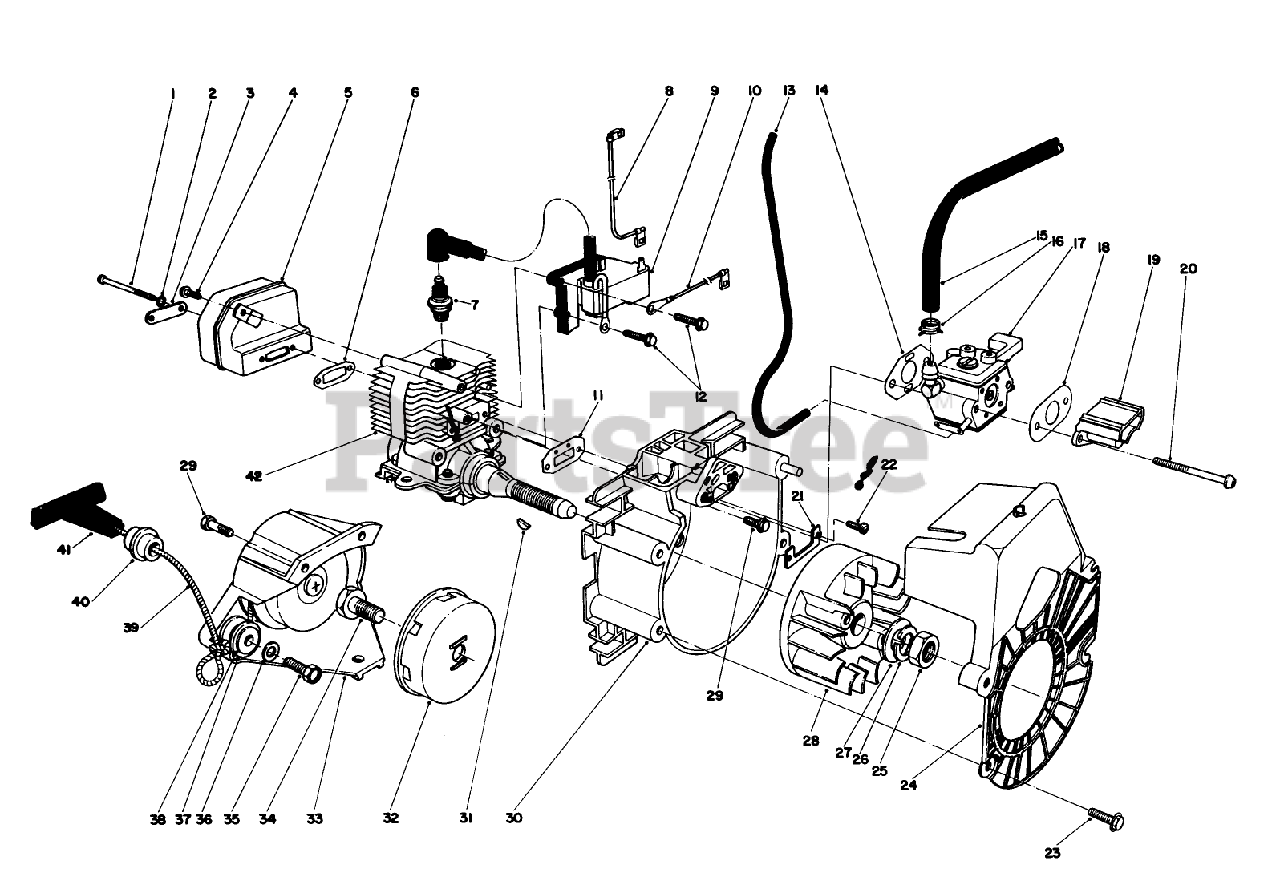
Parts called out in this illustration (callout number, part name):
1	MUFFLER SCREW
2	LOCKWASHER
3	Stress Plate, Muffler
4	Screw, Muffler Tab
5	Muffler Assembly
6	EXHAUST GASKET
7	SPARK PLUG
8	Wire Assembly-Coil
9	BIM Module
10	Wire Assembly-Ground
11	INTAKE GASKET
12	Screw CDI
13	HOSE-PRIMER
14	CARB. GASKET
15	Hose Fuel
16	CLAMP-HOSE
17	Carburetor
18	CHOKE GASKET
19	Spit Back Cup
20	Screw-Carburetor
21	Plate-Stress
22	Screw lntake
23	Screw-Shroud
24	Cooling Shroud
25	NUT-JAM
26	Lockwasher-Flywheel
27	Washer, Flywheel
28	Flywheel
29	Screw
30	Backing Plate Assembly
31	FLYWHEEL KEY
32	Cup, Starter
33	Starter Assembly (Incl Ref. #35-41)
34	Spark Plug
35	Screw, Idler Pulley
36	Washer, Brake
37	Idler Pulley (Incl. Ref. #38)
40	Guide Rope
41	Handle
42	SHORT BLOCK ASM
